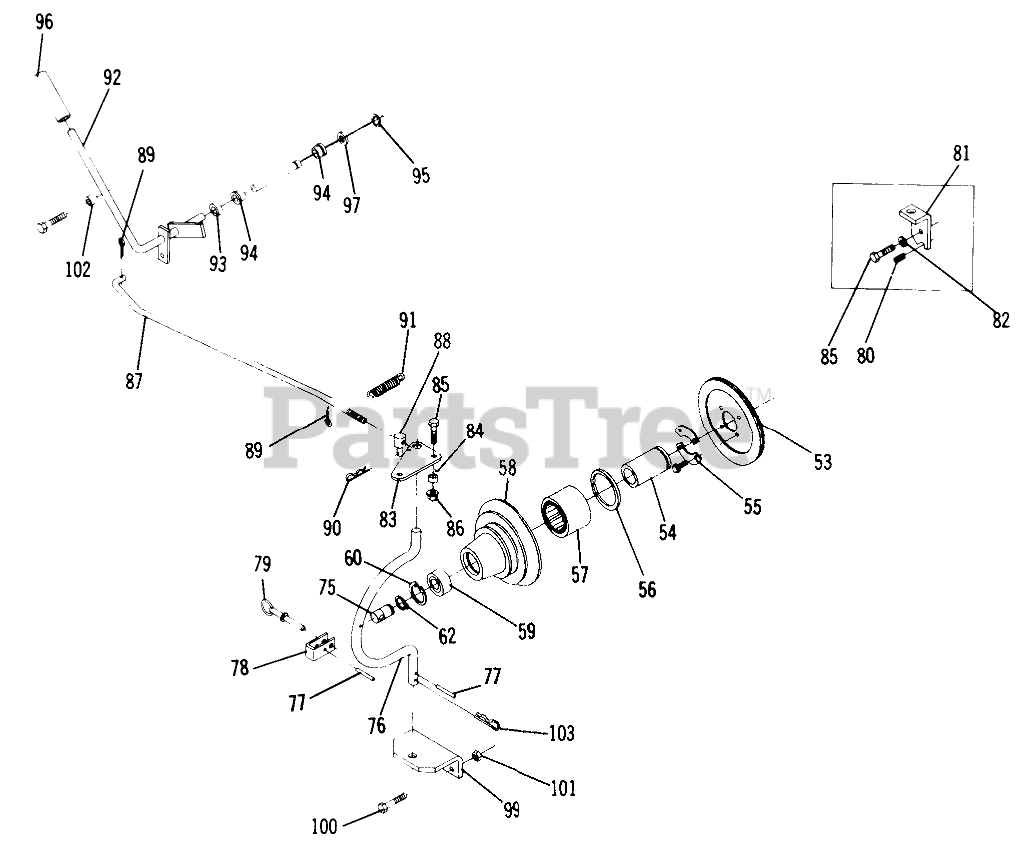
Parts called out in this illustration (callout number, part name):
14-53	Clutch Plate & Facing
14-54	BEARING RACE
14-55	RETAINER
14-56	SEAL-OIL
14-57	Seal
14-58	Housing-Clutch
14-59	Bearing
14-60	Ring-Snap
14-62	RING-SNAP, EXTERNAL
14-75	SHAFT-PTO
14-76	ROD HOUSING (NS)
14-77	PIN-SPIROL
14-78	Clevis
14-79	Pin
14-80	Set Screw 3/8-16 x 3/4
14-81	Bracket-Engine
14-82	Lockwasher
14-83	PLATE R
14-84	SPACER
14-85	Bolt 3/8-16 x 1
14-86	LOCKNUT-FLANGE
14-87	Clutch Rod
14-88	TRUNNION
14-89	Cotter Pin
14-90	Hairpin
14-91	Spring
14-92	Plug, Drain
14-93	SPACER
14-94	BUSHING-FLANGED
14-95	E Ring
14-96	GRIP
14-97	Washer
14-99	Axle
14-100	Bolt 3/8-16 x 1
14-102	Spacer
14-103	Hairpen
